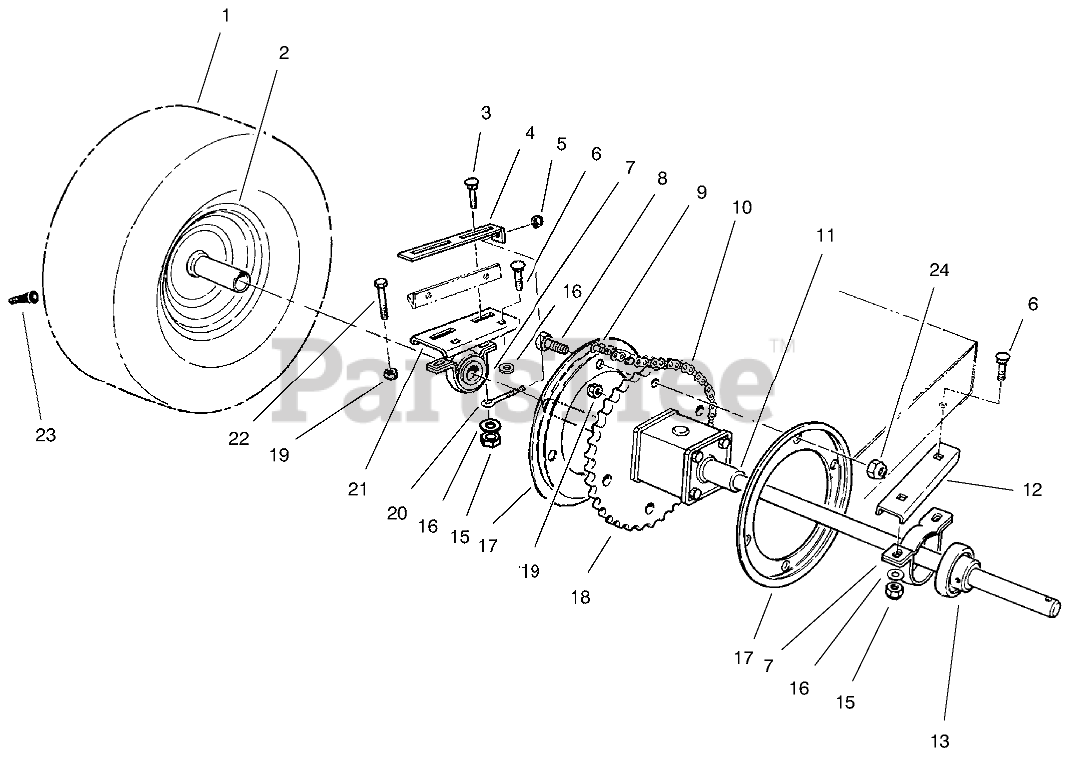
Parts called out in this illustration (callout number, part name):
1	TIRE,PNEU.13X5.00X6
2	WHEEL-REAR
3	SCREW-CARR
4	PLATE-ADJUSTING
5	NUT-LOCK, NI
6	BOLT-CARR
7	RTNR-PILLOW BLK
8	SCREW-HH
9	LINK-CHAIN
10	Chain (Incl. Ref. #9)
11	DIFFERENTIAL
12	LH AXLE SUPPORT (BLACK)
13	Bearing (Incl. Ref. #14)
15	NUT-LOCK, NI
16	WASHER-FLAT
17	GUIDE-REAR CHAIN
18	SPROCKET
19	NUT-LOCK, NI
20	SCREW-ADJUSTING
21	RH AXLE SUPPORT (BLACK)
22	AXLE MTG BOLT
23	STEM-VALVE
24	NUT-HEX
